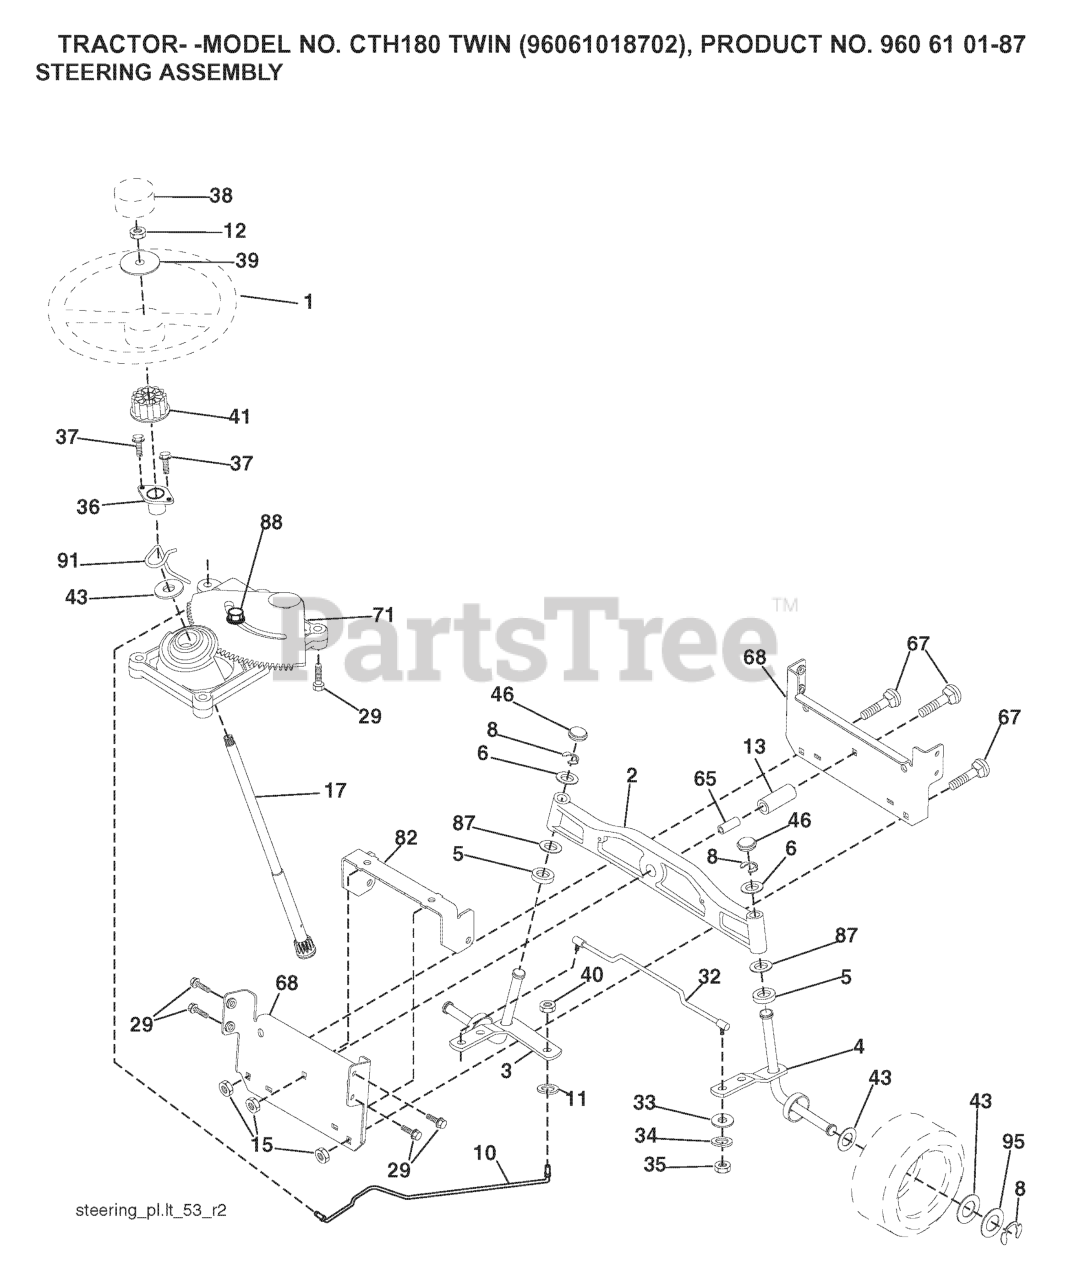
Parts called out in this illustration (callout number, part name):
1	STEERING WHEEL
2	AXLE ASSY FRONT
3	SPINDLE.ASM.LH.15"TIRES
4	SPINDLE.ASM.RH.15"TIRES
5	THRUST WASHER
10	DRAGLINK.15".TIRES.2001
11	WASHER, LOCK 3/8
12	NUT.HEX.1/2-20
13	TUBE, PIVOT AXLE
15	NUT
17	SHAFT ASM STRG
29	SCREW, 3/8-16X3/4
33	WASHER M
34	WASHER.LOCK.HVY.HLCL.SPR.5/16
35	NUT, CROWNLOCK
36	BUSHING, STRG. BLK
37	SCREW.TT.#10-32X.5.3/8.FLANGE
38	INSERT.CAP.STRG.WH.GRAY
39	WASHER 9/16"ID, 2 3/8"OD
40	NUT CROWNLOCK 3/8-24
41	ADAPTER, WHEEL STNG..
46	CAP.SPINDLE.BLACK
65	SPACER BRACE AXLE
67	BOLT CARRIAGE
68	BRACE.AXLE.15"TIRES
71	STEERING ASM
82	BRACKET.SUSP.CHASSIS.FRONT.15
87	WASHER, FLAT .781 X 1 1/2"
88	BOLT, SHOULDER 7/16-20
91	CLIP.STEERING
95	WASHER.HARDENED
